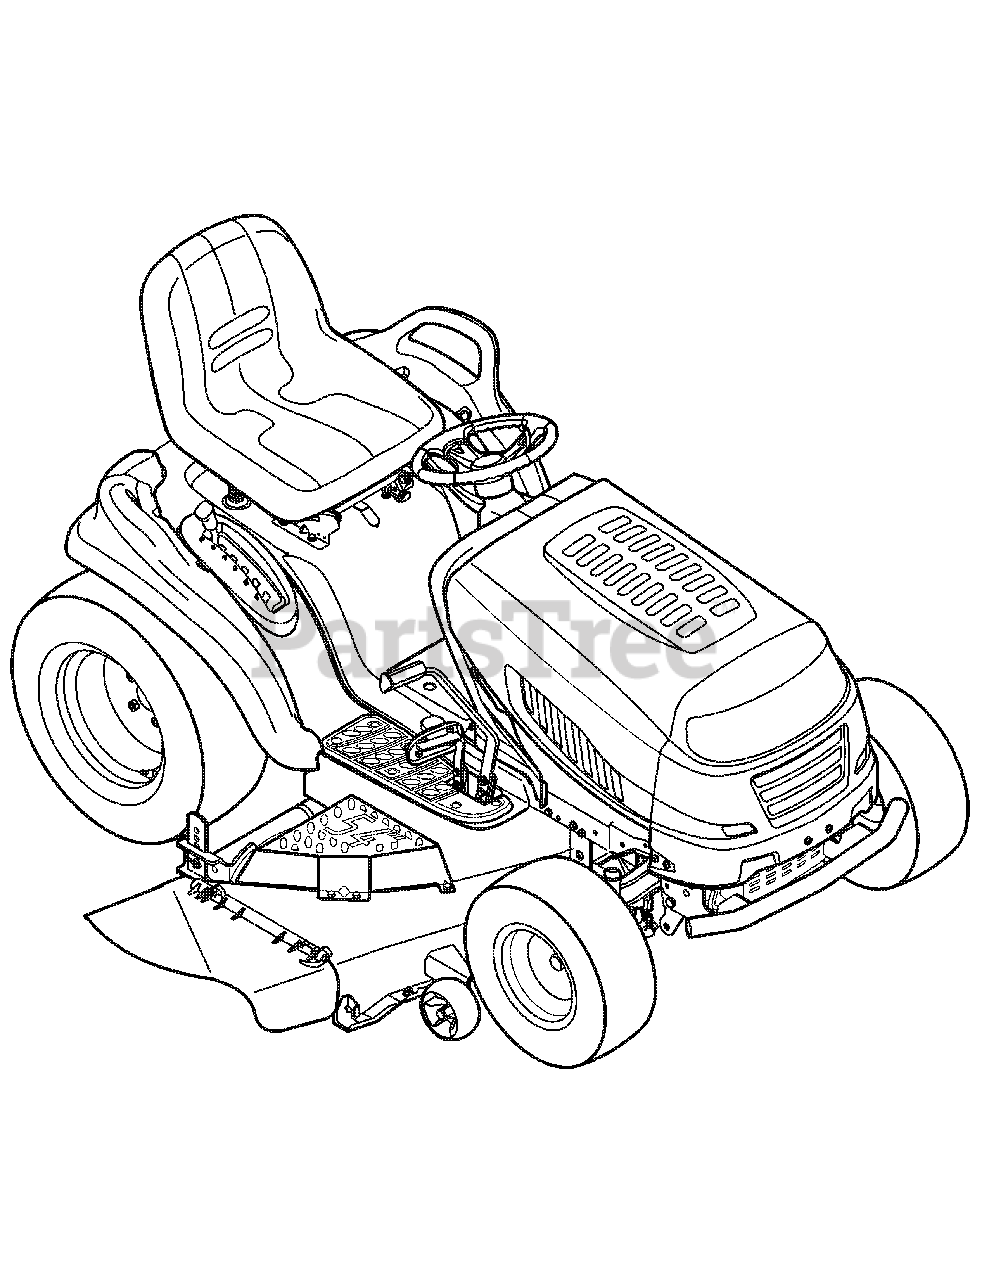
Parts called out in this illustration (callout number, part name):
19A-102	Steel Cart, 16 Cubic Foot
190-032	42-inch Two-stage Snow Thrower
190-285	Triple Bagger Grass Collector
190-784	Wheel Weights
